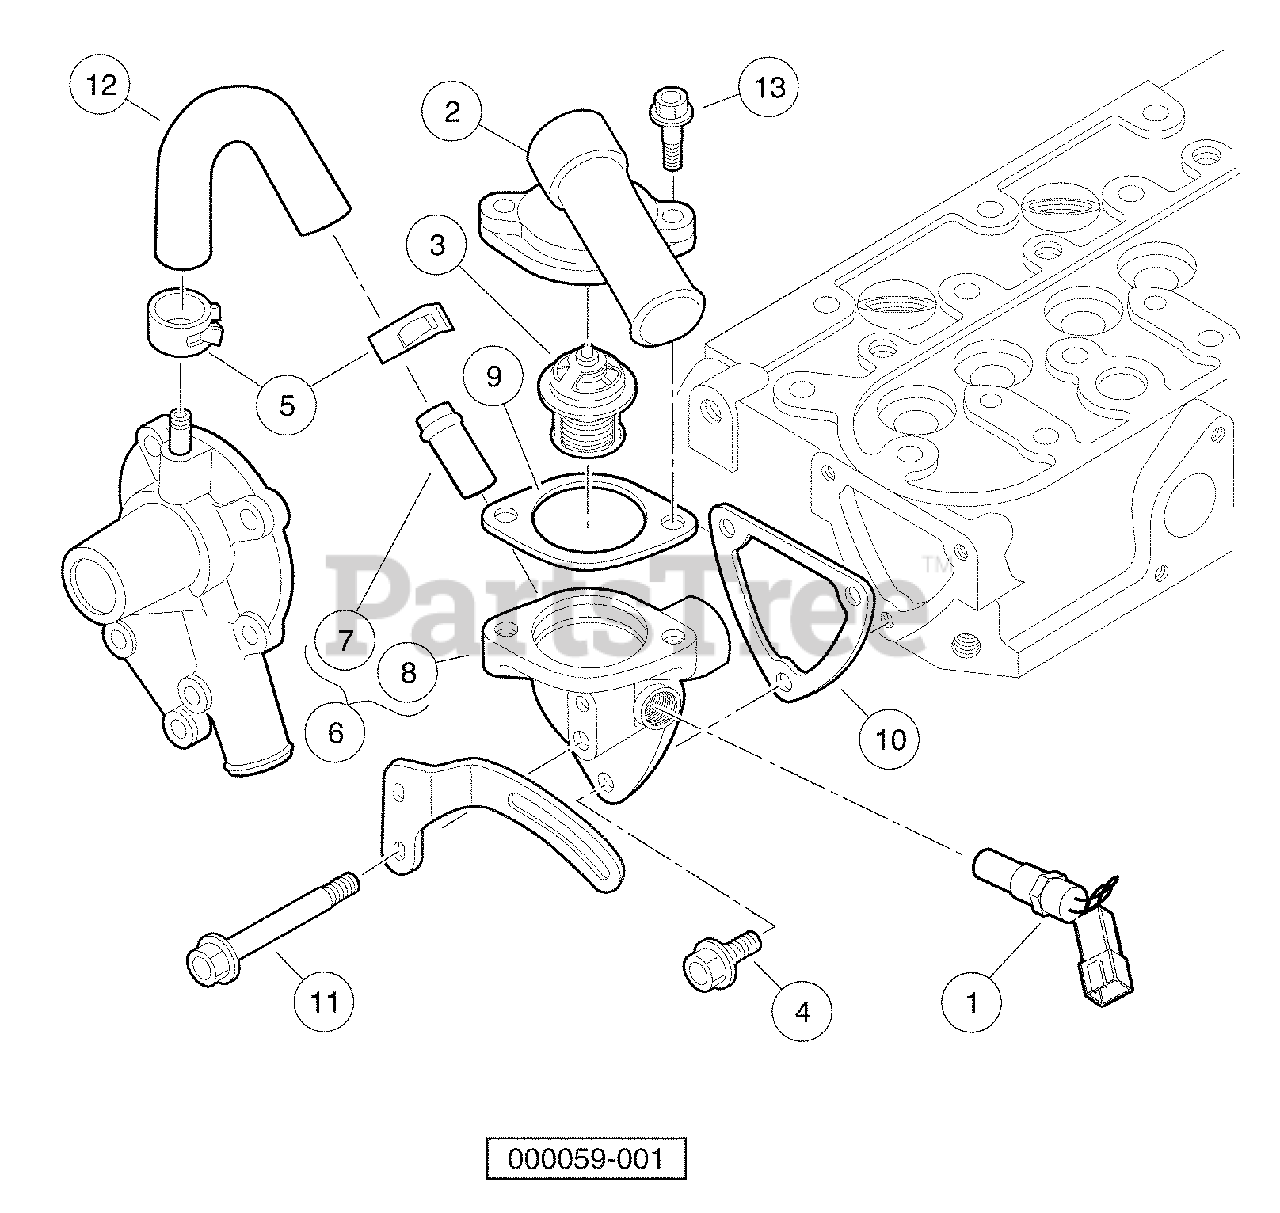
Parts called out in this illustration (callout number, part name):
1	Sensor, Coolant Temp
2	Cover, Thermostat
3	Assy, Thermostat
4	Bolt, M6 X 1 X 20
5	Band, Pipe
6	Flange, Water
7	Pipe, Water Return, D722
8	Flange, Water
9	Gasket, Thermostat
10	Gasket, Water Flange
11	Bolt, Alt, D722, Stay Lower
12	Pipe, Water Return, D722
13	Bolt, D722, Thermostat Cover
